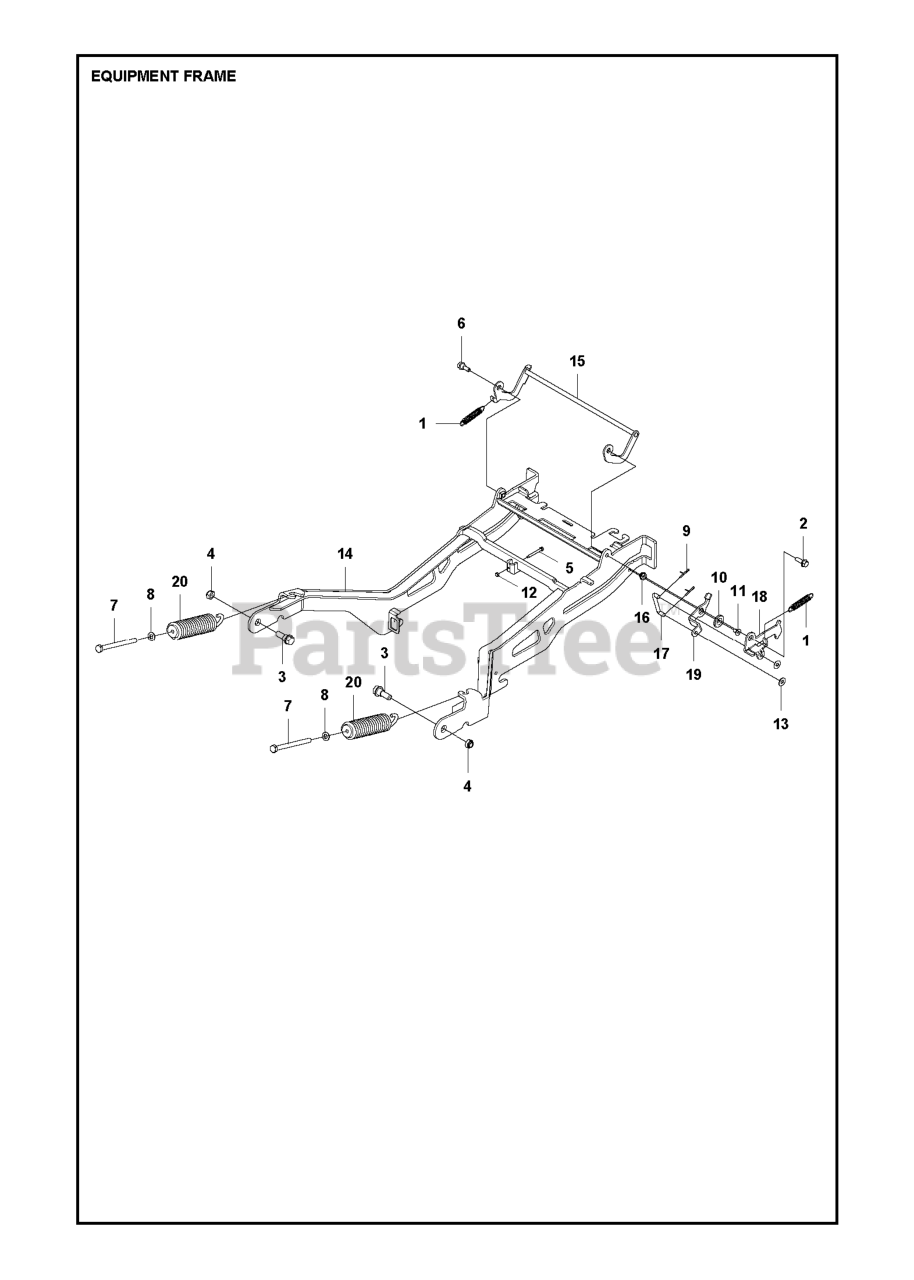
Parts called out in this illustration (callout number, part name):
2	BOLT
8	WASHER
11	SCREW IHCSFM
12	LOCKNUT M5
